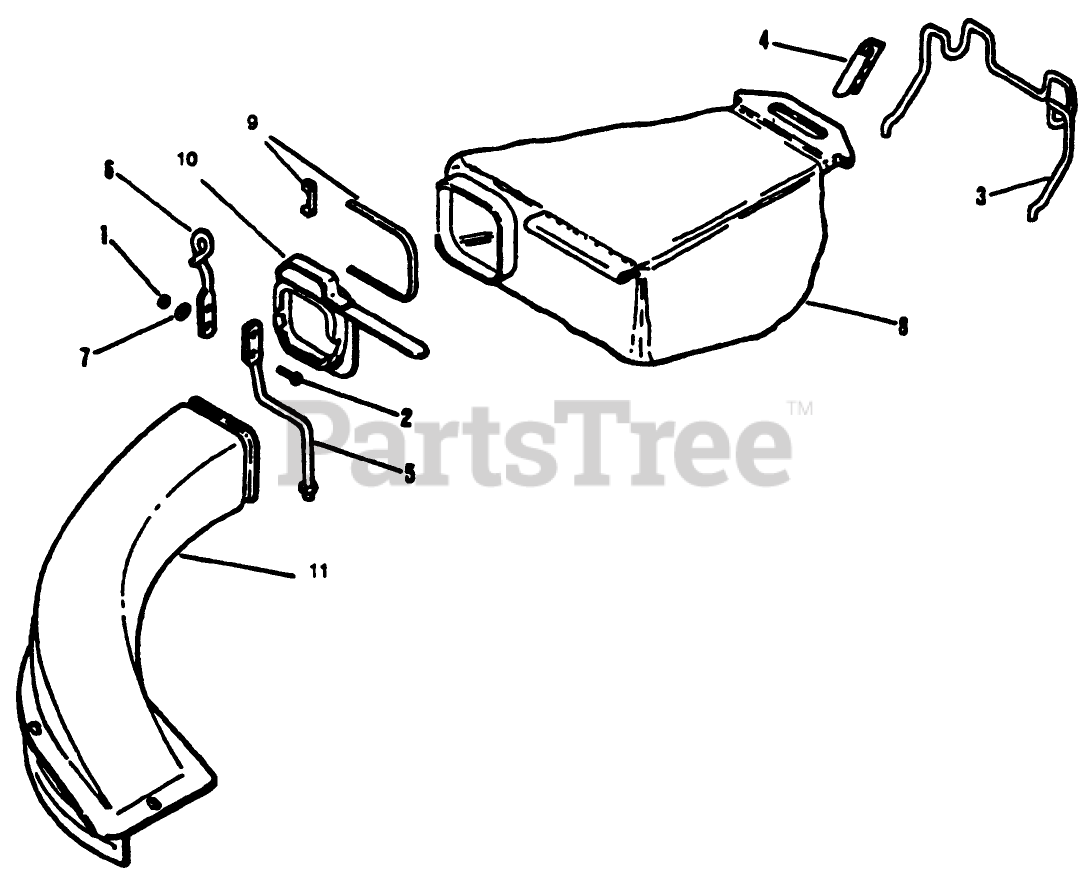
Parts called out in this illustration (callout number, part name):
1	LOCKNUT E
3	HANGER-WIRE
4	HANGER NARROW
11	REAR CATCHR CHUTE
